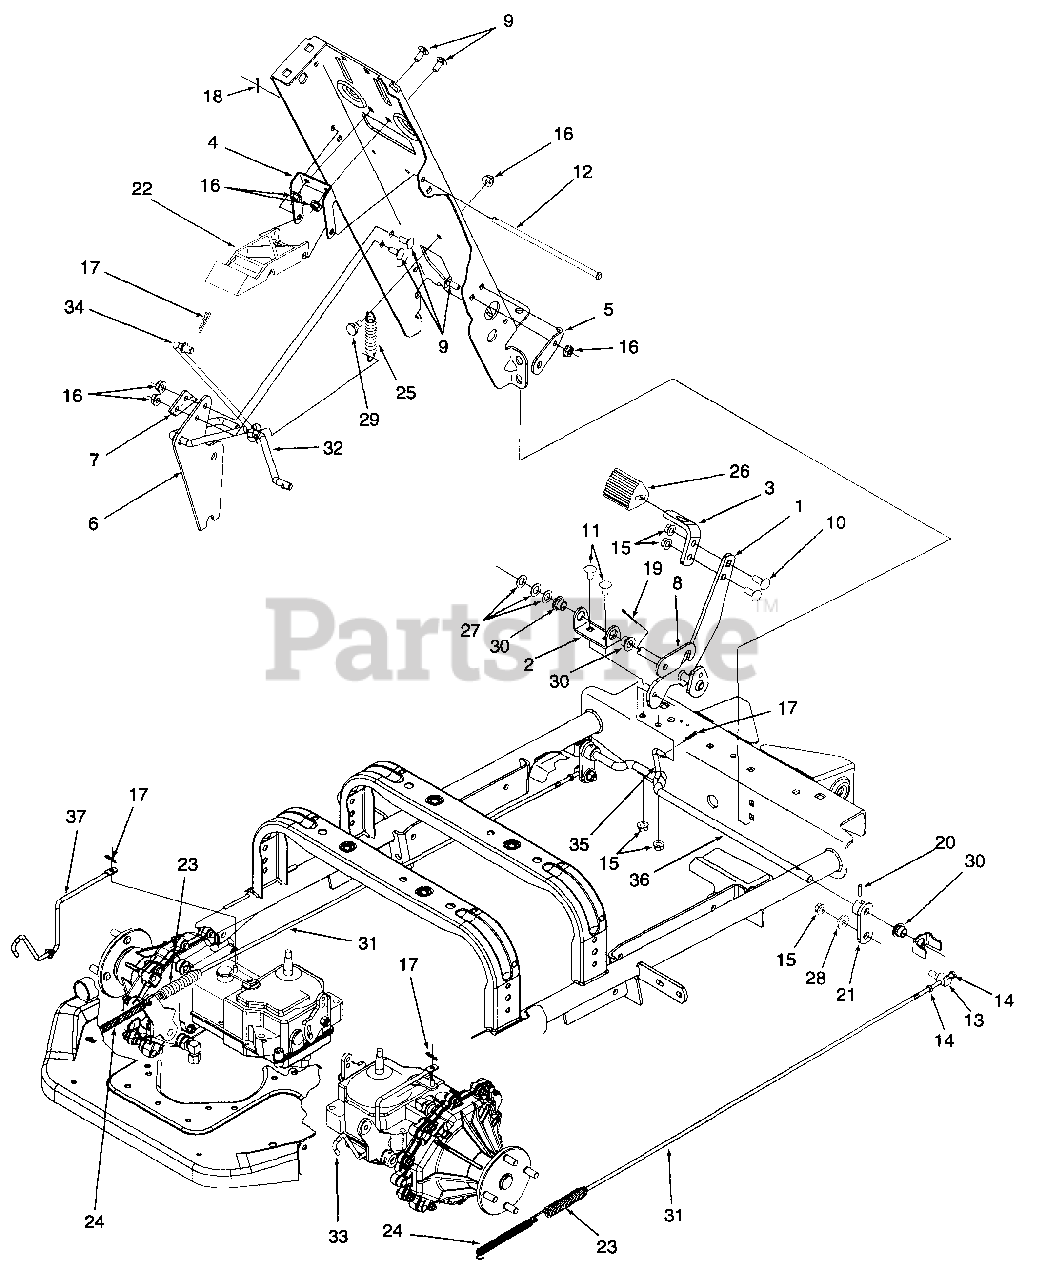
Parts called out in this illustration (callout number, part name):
10	Bolt, Carriage, 3/8-16 x 1.0 GR5
11	Bolt, Carriage, 3/8-16 x .75 GR5
12	Pin, Clevis, 1/4 x 6.65
14	Nut, Hex Jam 1/4-28
15	Nut, Hex Flange Lock, 3/8-16
16	Nut, Hex Flange Lock, 1/4-20
17	Pin, Internal Cotter
18	Pin, Cotter, 1/16 x .75
19	Pin, Cotter, 3/32 x 1.25
20	Pin, Spiral, 3/16 x 1.0
21	Arm, Brake
22	Lever, Park Brake Engagement
23	Spring, Extension, .75 O.D. x 5.0
24	Spring, Extension
25	Spring, Extension, 5 O.D. x 2.25
26	Foot Pad Brake
27	Washer, Flat, .536 x .930 x .05
28	Washer, Flat, .385 x 1.0 x .135
29	Bolt, Shoulder, .340 x .285:1/4-20
30	Bearing, Hex Flange, .506 I.D.
31	Rod, Brake
32	Rod, Park Brake Retaining
33	Rod, Hydro Pump Release RH
34	Rod, Park Brake
35	Rod, Park Brake Support
36	Rod, Brake Connecting
37	Rod, Hydro Pump Release LH
